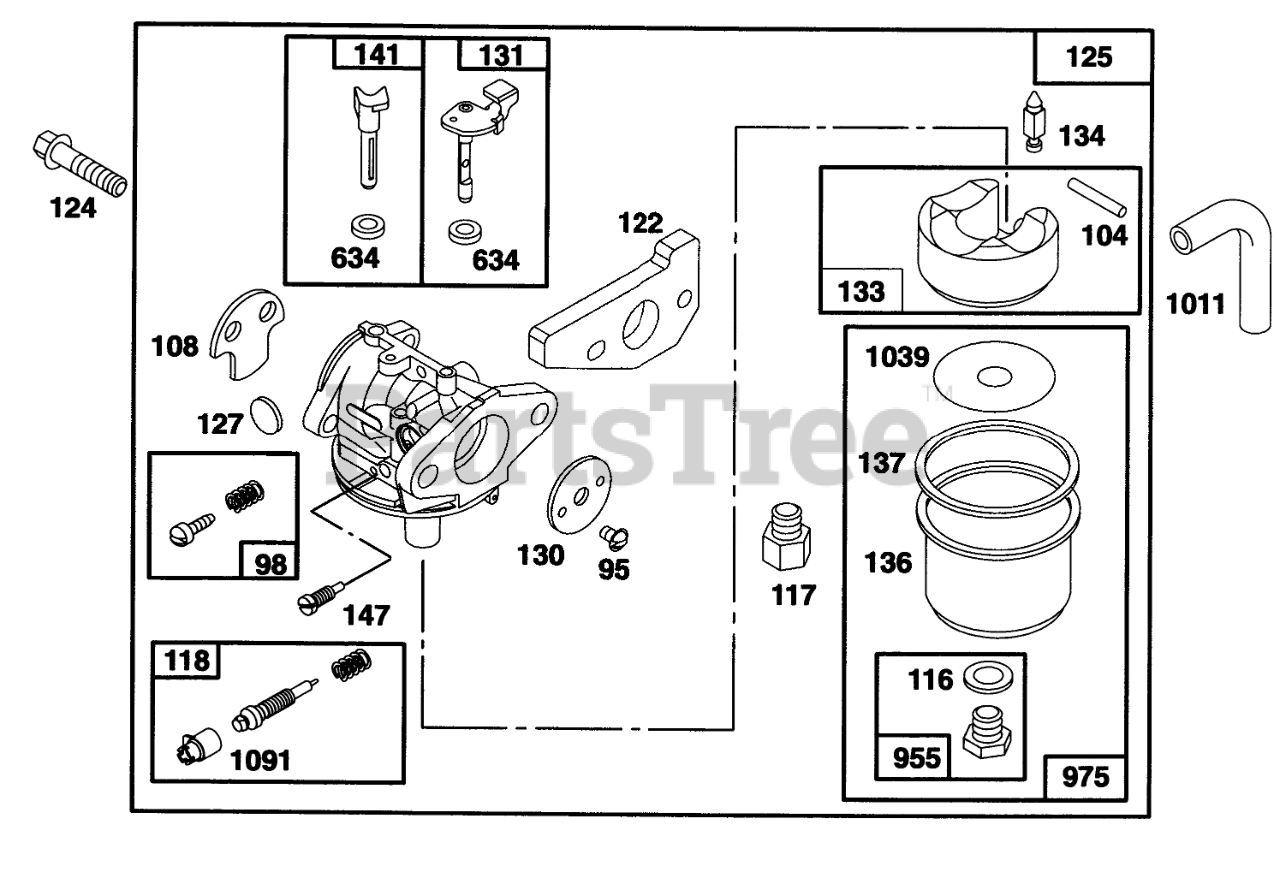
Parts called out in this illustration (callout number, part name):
95	SCREW - ROUND HEAD
98	IDLE ADJUSTING SCREW
104	FLOAT HINGE PIN
108	VALVE - CHOKE
116	SEALING GASKET
117	Jet-Main
118	VALVE/SPRING - NEEDLE
122	ADAPTER ASSEMBLY
124	HEX HEAD SCREW
125	ASSEMBLY - CARBURETOR
127	PLUG
130	THROTTLE VALVE
131	THROTTLE SHAFT
133	FLOAT-CARBURETOR
134	Valve-Inlet (Includes Seat)
136	FLOAT BOWL
137	FLOAT BOWL GASKET
141	CHOKE SHAFT
147	JET - PILOT
634	SEAL WASHER
955	HEX HEAD SCREW
975	CARBURETOR BOWL ASM
1011	VENT TUBE
1039	FLOAT LIMITER
1091	CAP - LIMITER
